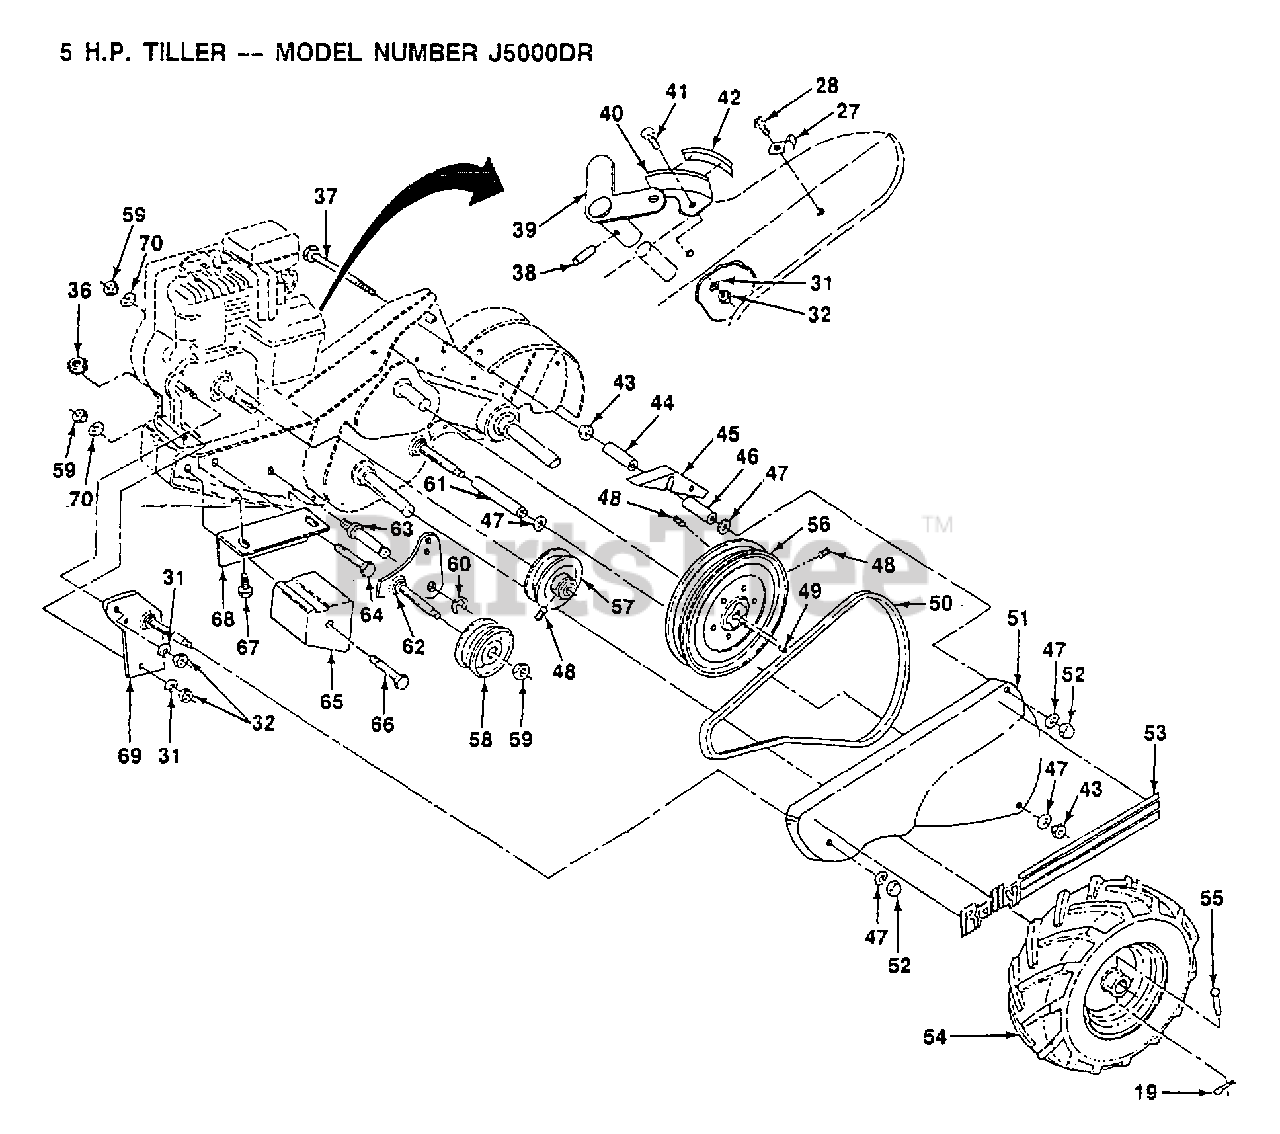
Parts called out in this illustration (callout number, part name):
39	LEVER ASM CRT
40	PANEL TI
41	BOLT
43	NUT.HEX.5/16-18
44	SPACER CRT
45	GUARD CRT
46	SPACER CRT
47	WASHER
48	SET SCREW
49	KEY T
52	NUT TI
53	DECAL, BELT GUARD
56	"SHEAVE 10"" CRT"
58	PULLEY-IDLER TI
59	NUT.HEX.3/8-16UNC
60	KLIP RING
61	SPACER
63	SHIFT ARM CRT
64	BOLT
65	COUNTERWEIGHT CRT
66	BOLT CRT
67	BOLT.HEX.5/16-1.5
68	BRACKET LH CRT
69	BRACKET ASSY CRT
70	LOCKWASHER
